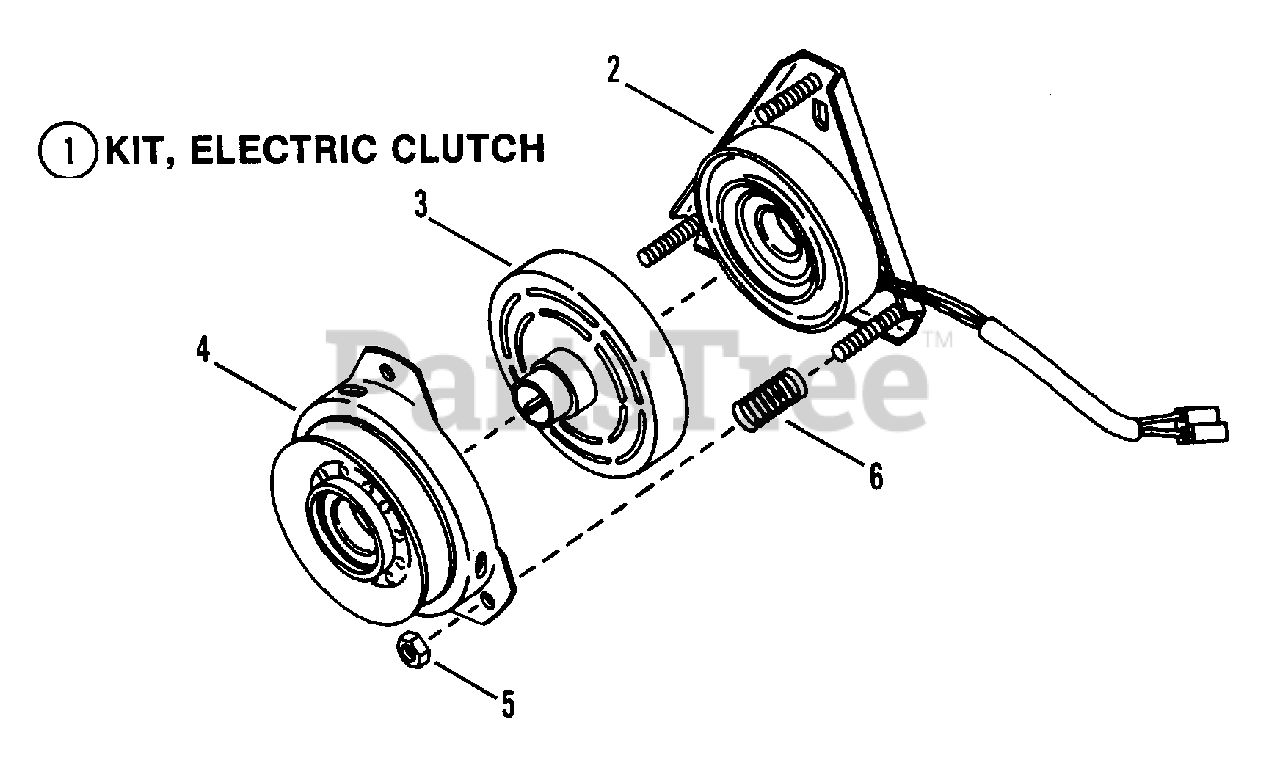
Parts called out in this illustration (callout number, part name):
1	KIT, Electric Clutch
2	FIELD COIL
3	ROTOR
4	ASSM'Y.,Arm Pulley
5	NUT, 3/8-24 Hex Lock
6	SPRING, Coil
